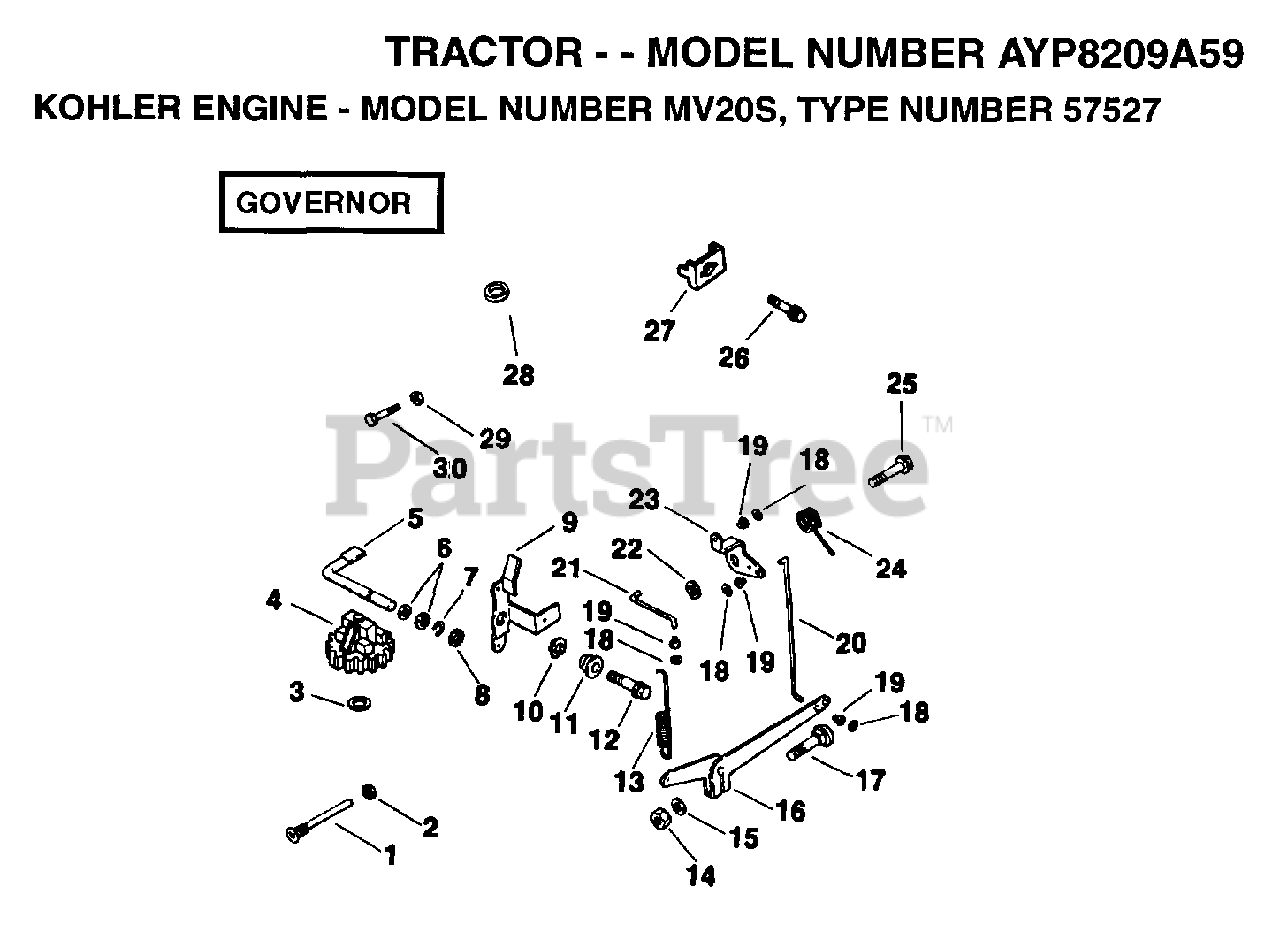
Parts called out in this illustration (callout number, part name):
8	WASHER, PLAIN 1/4
12	SCREW, 1/4-20 X 1
22	WASHER, PLAIN 1/4
25	SCREW, HEX 1/4-20 X 5/8
29	NUT, HEX #10-32
